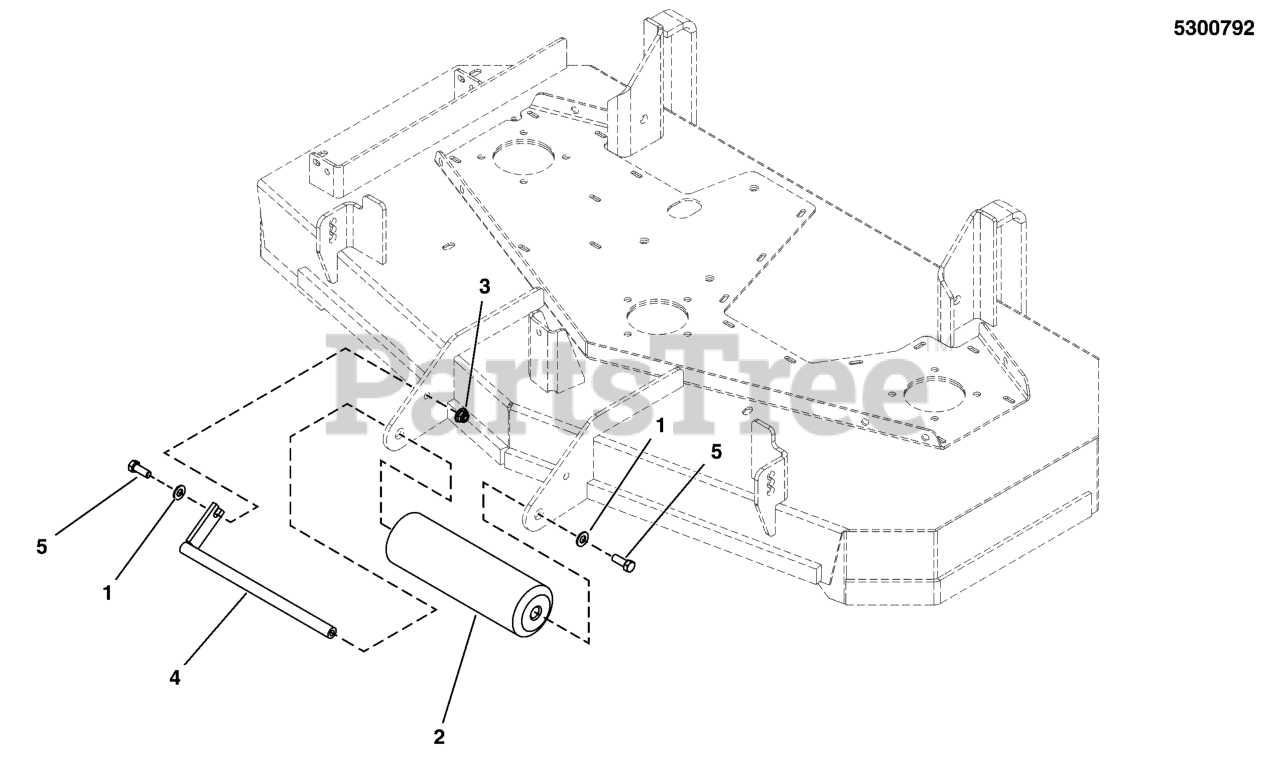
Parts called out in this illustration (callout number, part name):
1	WASHER, 3/8 SAE
2	ROLLER, DECK
3	NUT, 3/8-16 HEX NYLOCK FLANGE
4	PIN, ROLLER, CZ
5	BOLT, 3/8-16 X 1" GD5 CZ
